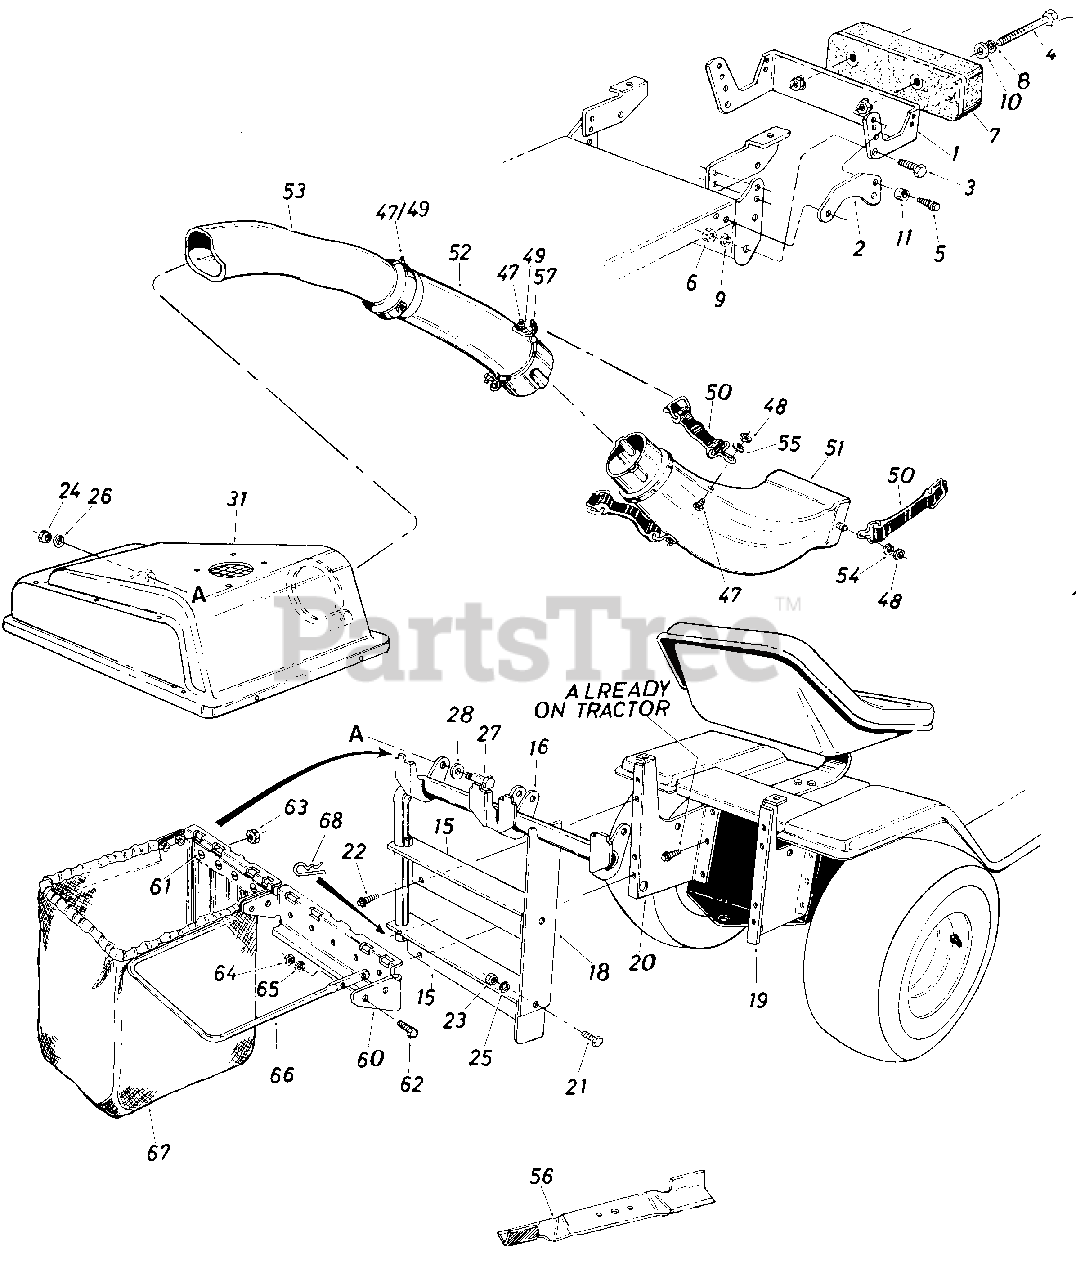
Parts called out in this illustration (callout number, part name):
1	Weight Brkt. Ass'y.
2	Weight Brkt. Tie Strap
3	Hex Bolt 7/16-20 x 1.0" Lg.*
4	Hex Bolt 3/8-16 x 4.5" Lg .
5	Hex AB Tap Scr. 5/16-18 x 1.0"
6	Hex Jam Nut 7/16-20 Thd.
7	Front Counter Weight 38 Ibs.
8	Bell.-Wash. 400" I.D. x .88" O.D.
9	L.-Wash. 7/16" I.D.*
10	Fl.-Wash. .390" I.D. x 1.12" O.D.
11	Spacer
15	Catcher Support Tube Mtg. Brkt.
16	Catcher Support Tube Ass'y.
18	Catcher Latch and Support Brkt.
19	Grass Catcher Support Brkt. - R.H.
20	Grass Catcher Support Brkt. - L.H.
21	Hex Bolt 5/16-18 x .75" Lg.*
22	Hex Self-Tap Scr. 1/4-20 x .62" Lg.
23	Hex Nut 5/16-18 Thd.*
24	Hex Nut 3/8-16 Thd.*
25	L.Wash. 5/16" I.D.*
26	L.Wash. 3/8" I.D.*
27	Shld. Bolt 3/8-16 x .500" Dia.
28	Bell.-Wash. .505" I.D. x 1.00" O.D.
31	Grass Catcher Cover Ass'y.
47	Hex Bolt 1/4-20 x .50" Lg.*
49	Hex Ins. L.-Nut 1/4-20 Thd.
50	Retainer Strap Ass'y.
51	Catcher Elbow
52	Catcher Tube
53	Discharge Chute
54	L.-Wash. .270" I.D. x .57" O.D.
56	High-Lift Blade 19.38" x 3"
57	Retainer Hook Brkt.
61	Truss Mach. Scr. #10-24 x .38" Lg.
62	Hex Bolt 1/4-28 x .75" Lg.
63	Hex Sems Nut #10-24 Thd.
64	Hex Nut 1/4-28 Thd .*
65	L.-Wash. 1/4" I.D.*
67	Grass Catcher Bag
68	Int. Cotter Pin
